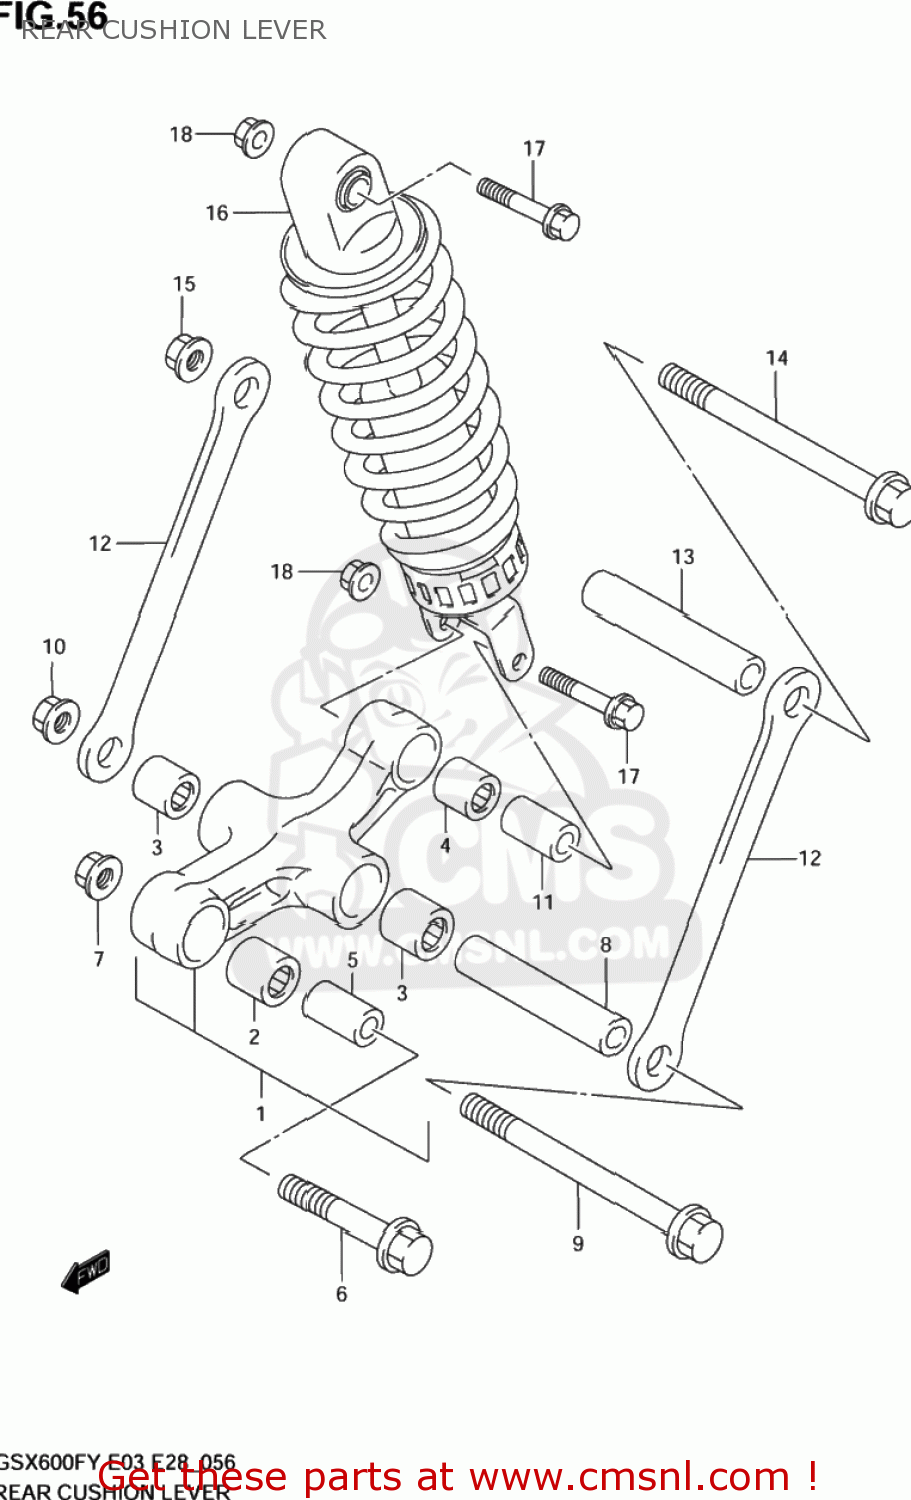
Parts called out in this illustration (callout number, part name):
1	LEVER SET,RR CUSHION
2	BEARING(20X27X30)
3	BEARING(20X27X23.5)
4	BEARING(17X24X26)
5	SPACER(14X20X34)
6	BOLT(14X62)
7	NUT
8	SPACER,RR CUSHION ROD
9	SHAFT,RR CUSHION ROD
10	NUT
11	SPACER,RR CUSHION LEVER
12	ROD,RR CUSHION
13	SPACER,RR CUSHION ROD
14	SHAFT,RR CUSHION ROD
15	NUT
16	ABSORBER ASSY,RR SHOCK
17	BOLT(10X52)
18	NUT
